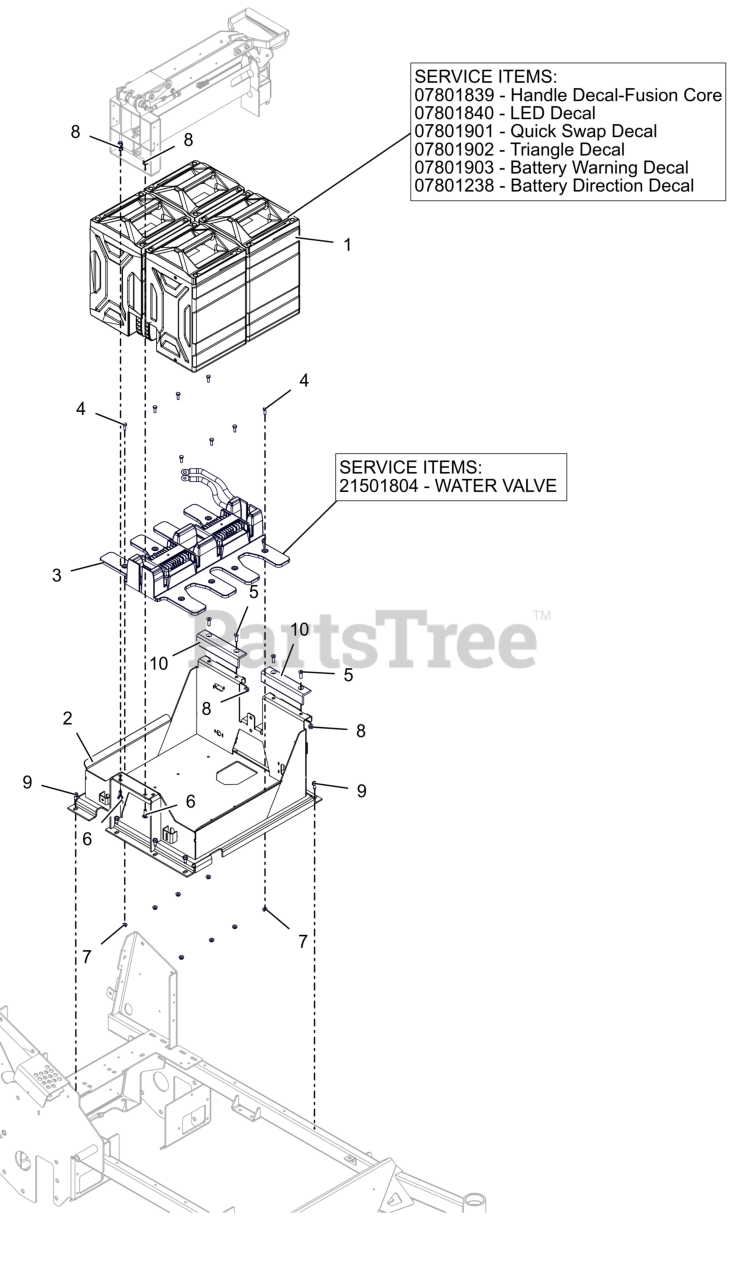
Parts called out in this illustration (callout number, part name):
1	KIT, EV BATTERY
1	HANDLE DECAL - FUSION CORE
1	LED DECAL
1	QUICK SWAP DECAL
1	TRIANGLE DECAL
1	BATTERY WARNING DECAL
1	DECAL, BATTERY INSTALL DIRECTION
2	WLDMT, BATTERY TRAY (ORANGE)
3	BASE, BATTERY BUSSBAR
3	VALVE, WATER
4	BLT, HEX .25-20X.75 G5 ZCC
5	SCR, MCH .312-18X1.00 SFH ZCC
6	BLT,RHSN .31-18X1.00 G5 ZCC
7	NUT-LK-CTR-FLG .25-20 ZC120
8	NUT,LK-CTR-FLG .31-18 GF ZCC
9	SCR,TAP .312-18X.75 HWH TR ZCC
10	EDGE, PROTECTIVE - BATTERY
